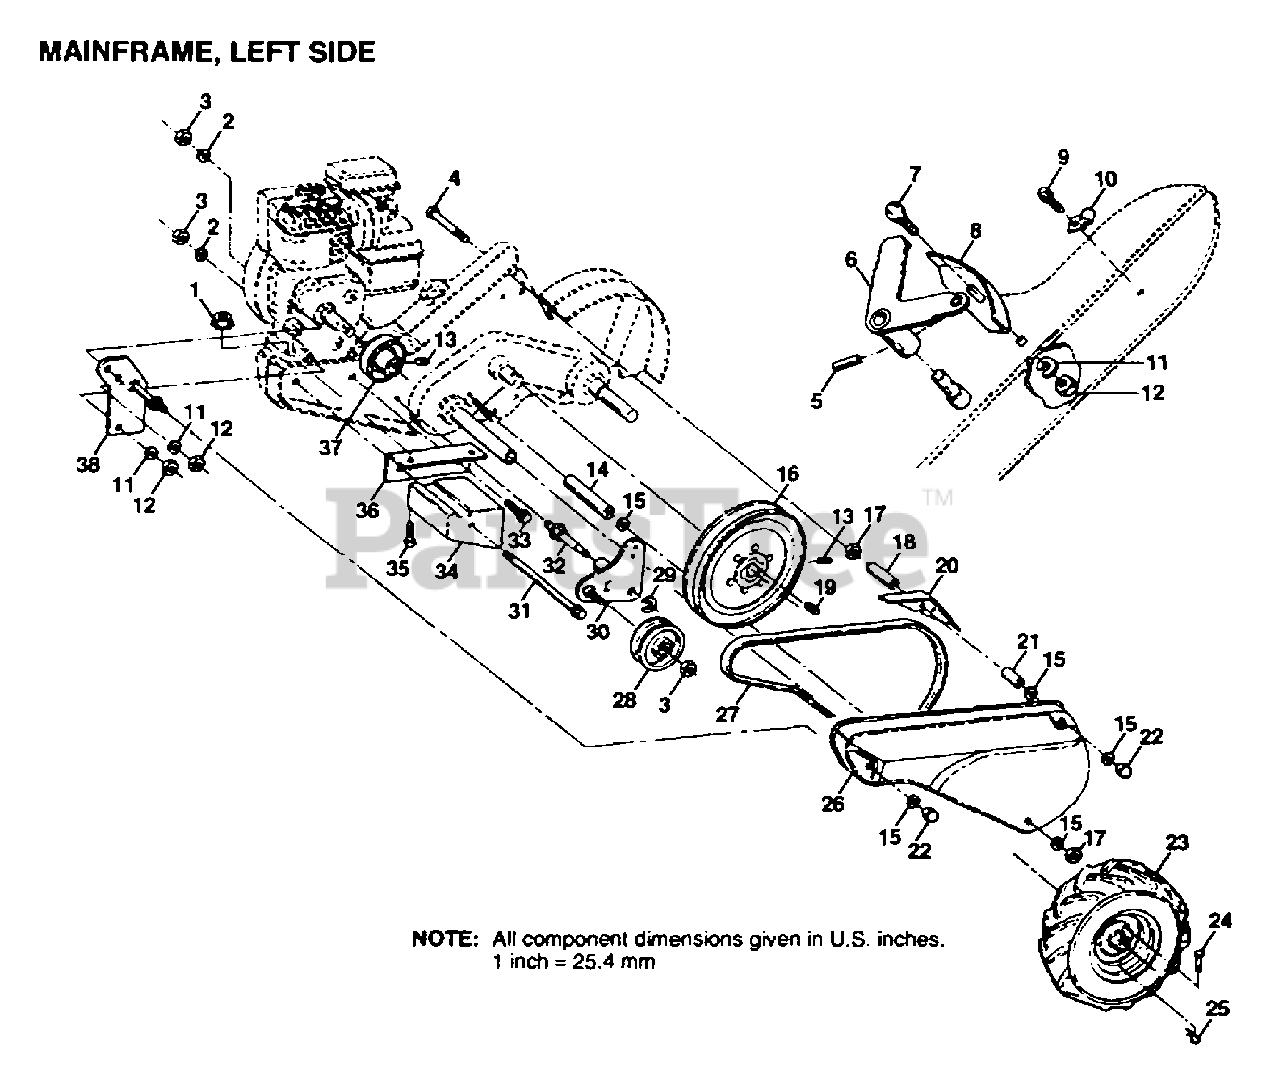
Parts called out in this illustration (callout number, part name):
2	LOCKWASHER
3	NUT.HEX.3/8-16UNC
4	BOLT TI
6	LEVER ASM CRT
7	BOLT
8	PANEL TI
10	CONDIUT CLIP T
11	LOCKWASHER
13	SET SCREW
14	SPACER
15	WASHER
16	"SHEAVE 10"" CRT"
17	NUT.HEX.5/16-18
18	SPACER CRT
19	KEY T
20	GUARD CRT
21	SPLIT SPACER
22	NUT TI
23	TIRE.CHV.13X5.0-6
24	RIVET.DRILL.1.75
25	RETAINER M
27	BELT-V
28	PULLEY-IDLER TI
29	KLIP RING
31	BOLT CRT
32	SHIFT ARM CRT
33	BOLT
34	COUNTERWEIGHT CRT
35	BOLT.HEX.5/16-1.5
36	BRACKET LH CRT
37	ENGINE SHEAVE
38	BELT GUARD BRKT
